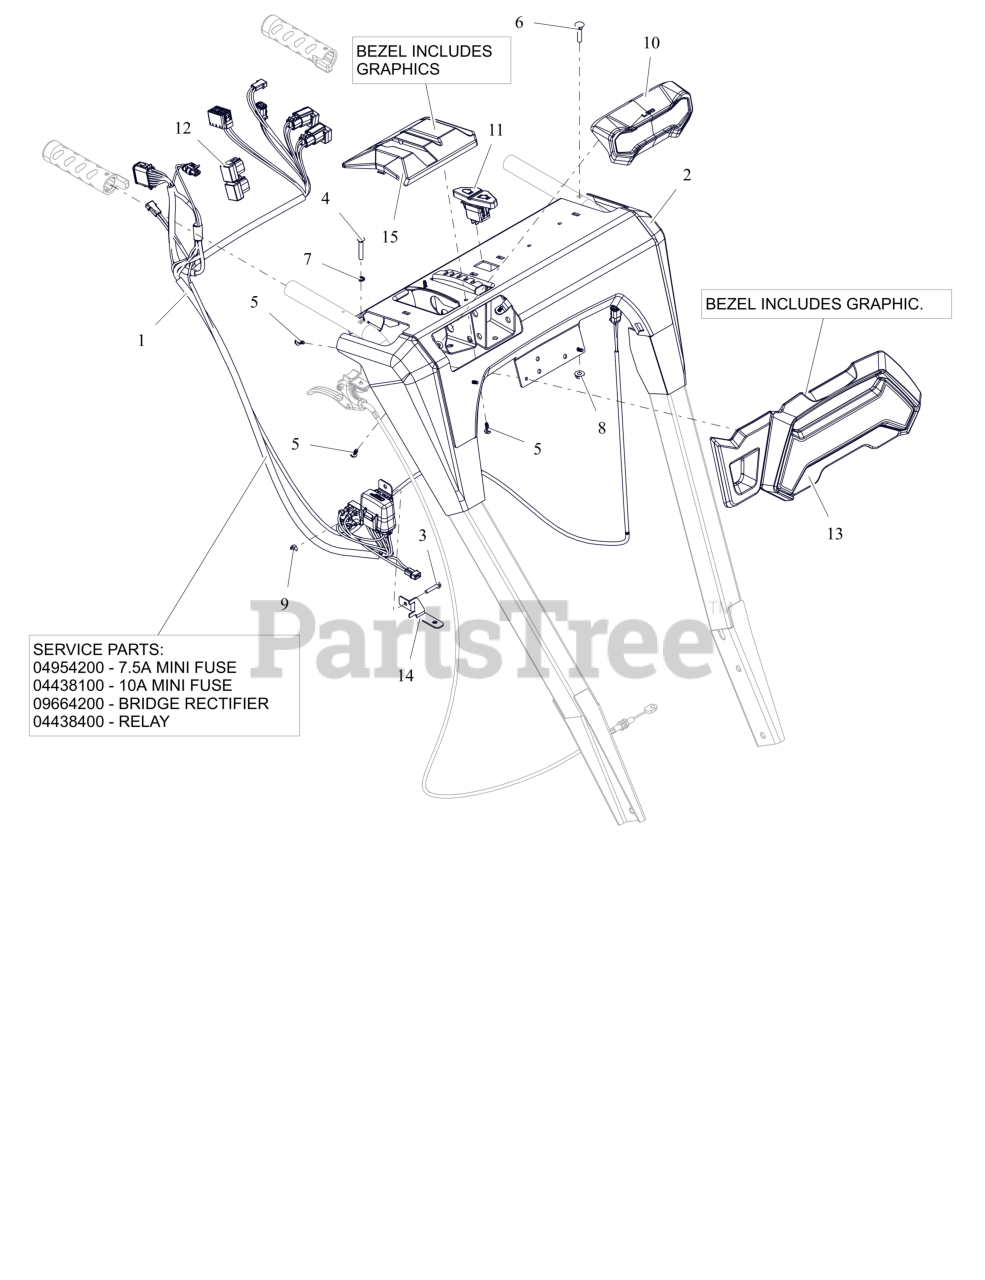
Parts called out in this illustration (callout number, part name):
1	HARNESS- WIRE - LT HG ECHUTE
1	FUSE, 7.5 AMP MINI-ATC
1	FUSE,10 AMP MINI-ATC
1	RECTIFIER, BRIDGE
1	RELAY,MICRO5 TERML W/RESISTOR
2	PANEL, DASH-HYDRO ECR W/DECAL
3	BLT, HWH #10-24X1.00 ZCC
4	SCR,OVAL .25-20X1.50 ZCC
5	SCR, PLASTIC #10X.50
6	BLT-RDHDXLSQNK.25-20X1.25 G5ZC
7	WSHR-LK-INT .250 TH TYA
8	NUT-LK-CTR-FLG .25-20 ZC120
9	NUT-LK-NYL #10-24 G2 ZCC
10	HEADLIGHT ASM- LED
11	SWITCH- ROCKER SPST-ON/OFF
12	PACK, DIODE
13	BEZEL- LARGE - PROFESSIONAL
14	BRKT, MOUNT RECTIFIER
15	BEZEL, SHIFT HYDRO TRACK DECAL
